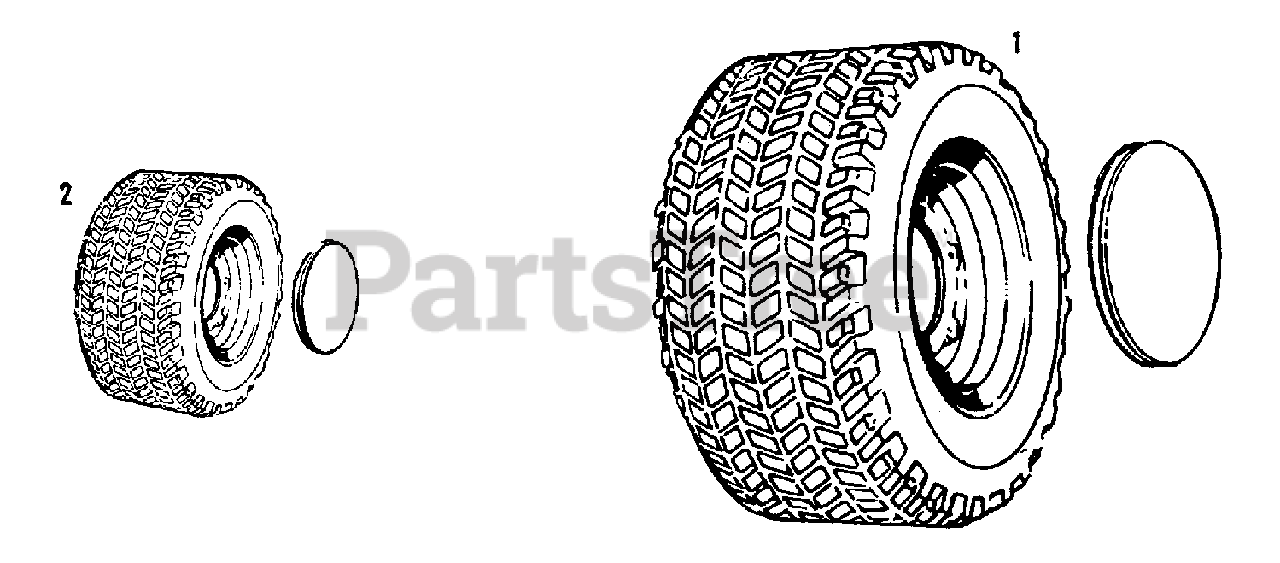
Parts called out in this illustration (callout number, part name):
1	WHEEL, Rear (10 H.P. Tractors)
1	TIRE, Tubeless (23 x 8.50-12, 2 Ply)
1	TUBE, (F/23 x 8.50-12 Tires)
1	WHEEL, Rear (16 H.P. Tractors)
1	TIRE, Tubeless (23 x 10.50-12, 2 Ply)
1	TUBE, (F/23 x 10.50 x 12 Tires)
2	WHEEL, Front (10 H.P. Tractors)
2	TIRE, Tubeless (4.80/4.00-8, 2 Ply)
2	WHEEL, Front (16 x 6.50-8)(10 H.P.) (Eff. S/N 25841001 & Up; 29941001 & Up)
2	TIRE, Tubeless (16 x 6.50-8, 2 Ply)(Eff. S/N 25841001 & Up; 29941001 & Up)
2	TUBE, 16 x 6.50 x 8(Eff. S/N 25841001 & Up; 29941001 & Up)
2	VALVE STEM & CAP(Eff. S/N 25841001 & Up; 29941001 & Up)
2	TUBE (F/4.80/4.00-8 Tires
2	WHEEL, Front (16 H.P. Tractors)
2	TIRE, Tubeless (16 x 6.50-8, 2 Ply)
2	TUBE, (F/16 x 6.50-8 Tires)
3	BOLT, Wheel Hub
